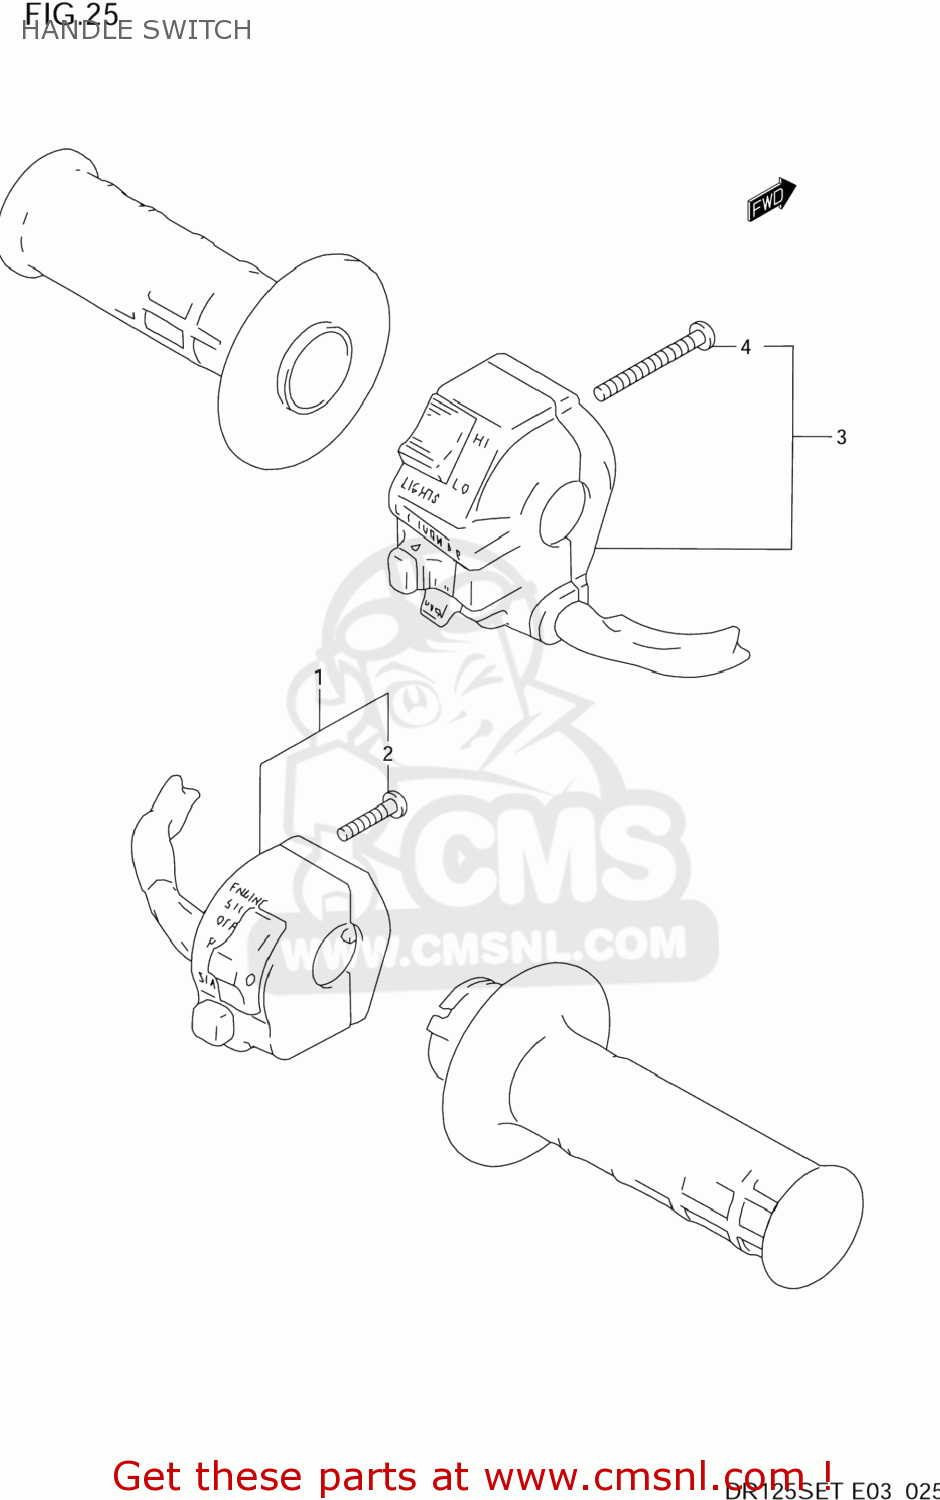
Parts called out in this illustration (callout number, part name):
1	SWITCH ASSEMBLY,HANDLE,RIGHT
2	SCREW
3	SWITCH ASSEMBLY,HANDLE,LEFT
4	SCREW
